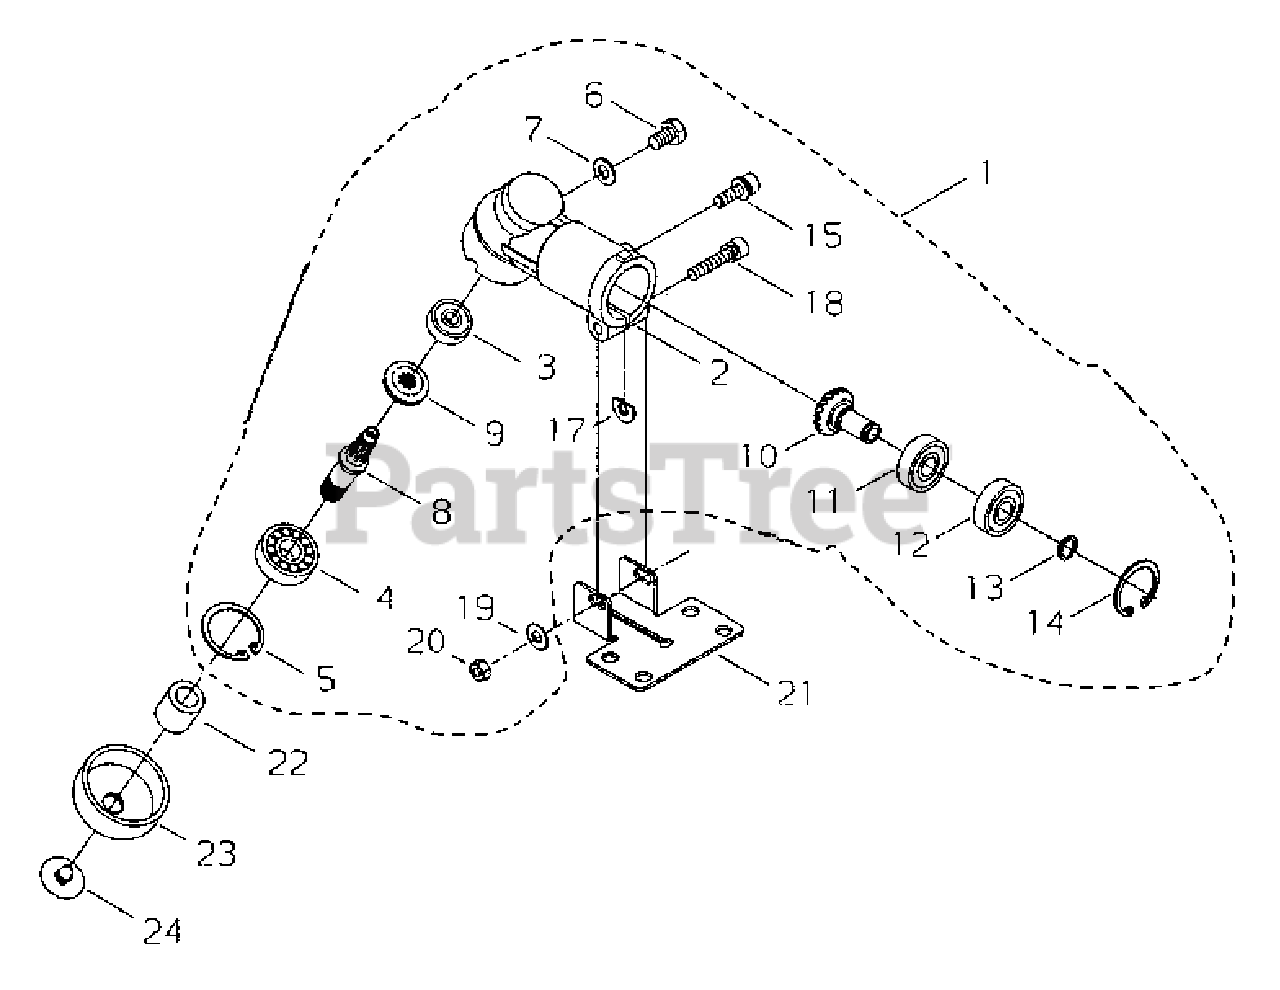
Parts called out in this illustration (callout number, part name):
1	GEAR CASE SUB ASSY
2	HOUSING, GEAR CASE
3	BEARING, BALL 626
4	BEARING, BALL 6000 DDU
5	RING, SNAP Ø26
6	BOLT M6×10
7	WASHER
8	SHAFT, GEAR
9	GEAR, BEVEL
10	GEAR, PINION
11	BEARING, BALL 608
12	BEARING, BALL 608ZZ
13	RING, SNAP
14	RING, SNAP Ø22
15	BOLT M5×16
17	D-WASHER
18	BOLT M5×35
19	WASHER 5 MM
20	NUT M5
21	PLATE, SHIELD MOUNTING
22	COLLAR
23	HOLDER
24	CLIP
